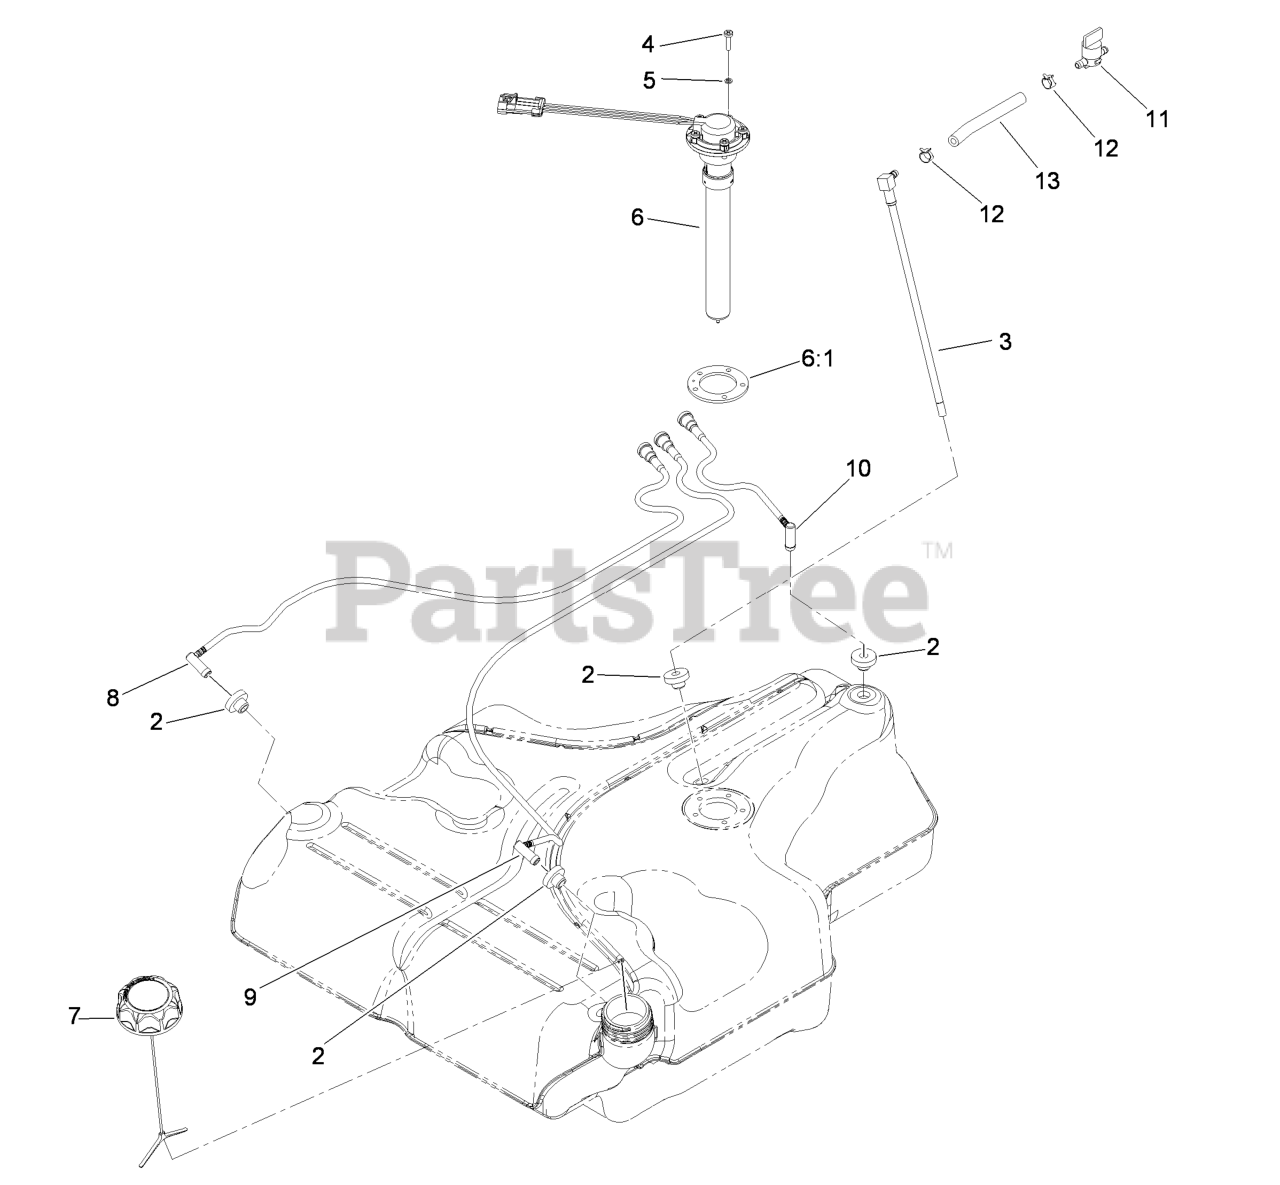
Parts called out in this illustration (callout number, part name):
2	BUSHING
3	FUEL LINE KIT (WITH GROMMET)
4	SCREW-PAN
5	WASHER-LOCK
6:1	GASKET-SENDER, FUEL
8	RH VENT LINE KIT (WITH GROMMET)
9	LH VENT LINE KIT (WITH GROMMET)
10	REAR VENT LINE KIT (WITH GROMMET)
11	VALVE-FUEL
12	CLAMP-HOSE
13	HOSE-FUEL
